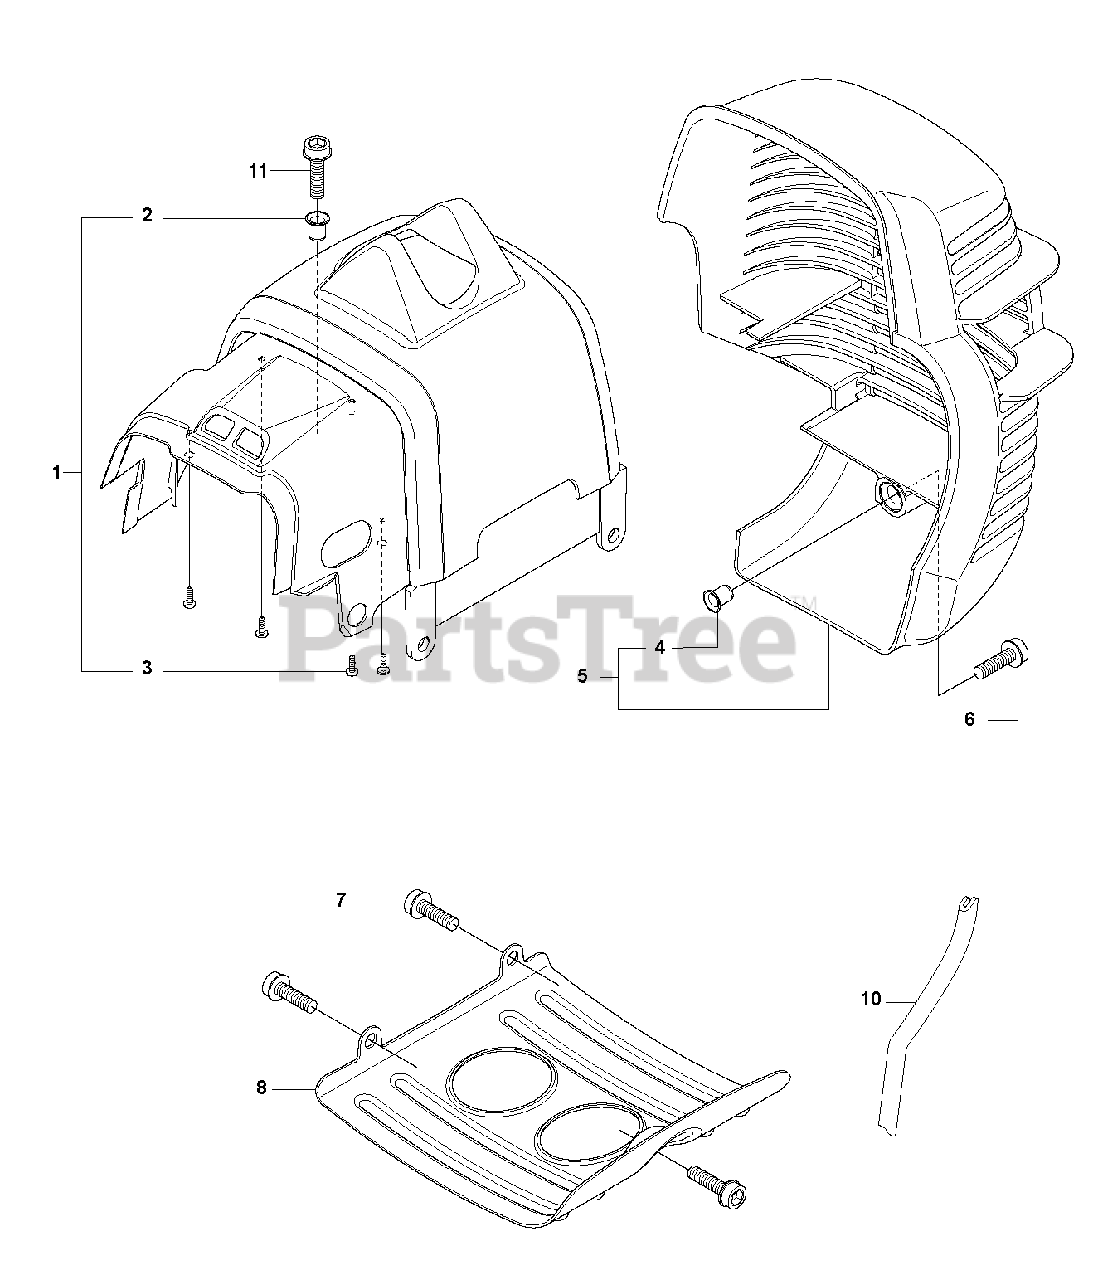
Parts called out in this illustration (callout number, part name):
2	SLEEVE
3	SCREW
4	SLEEVE
